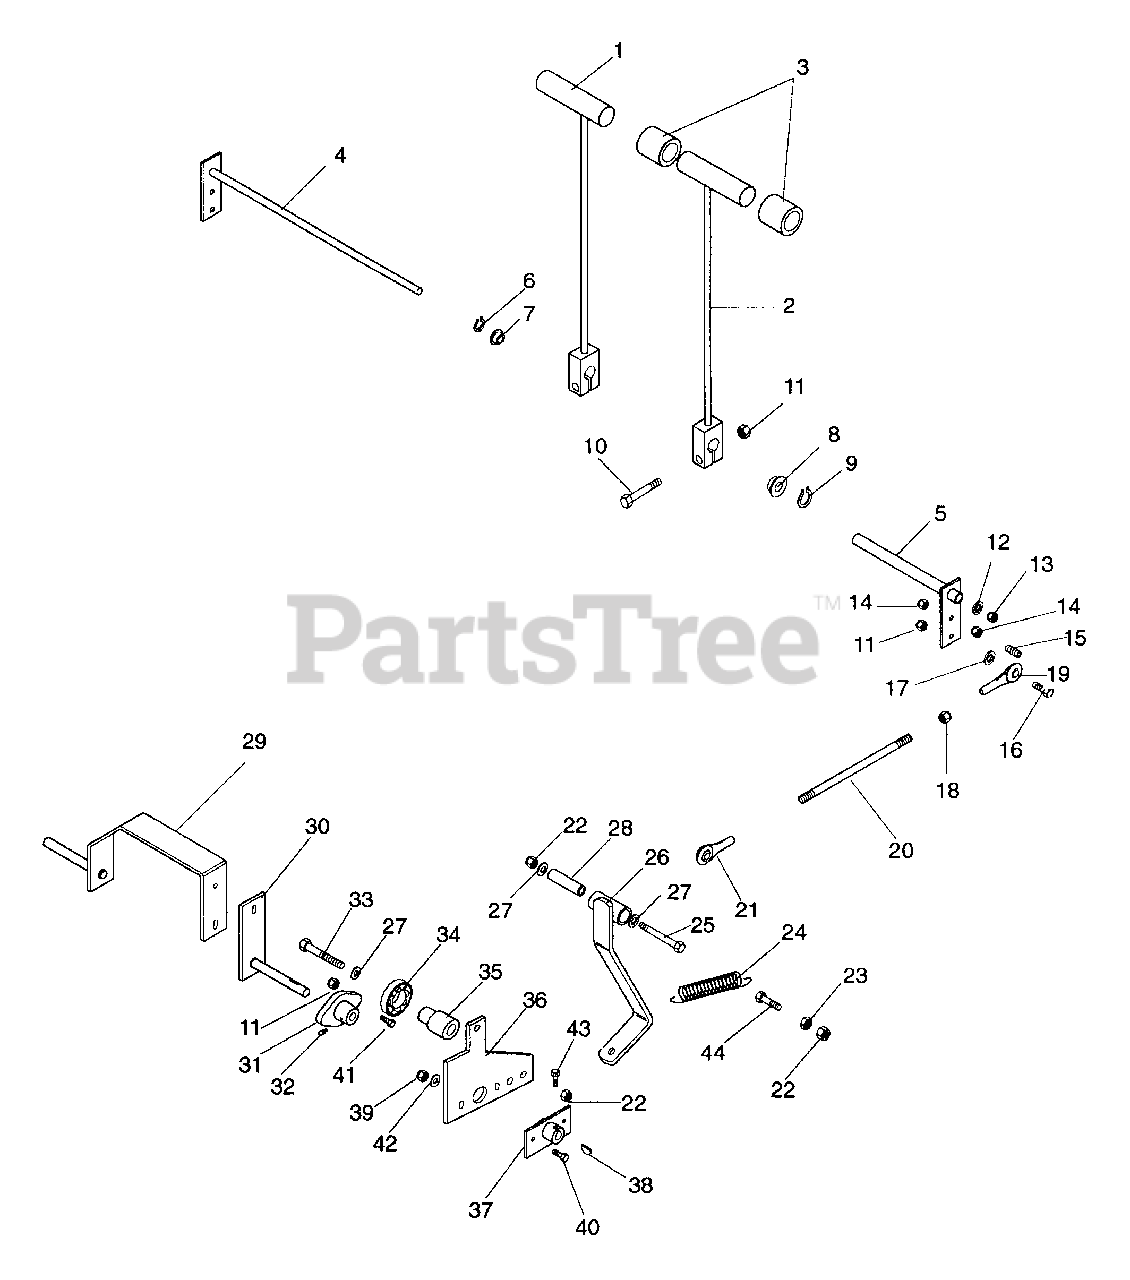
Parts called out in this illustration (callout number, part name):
1	Weldment, Steering Lever L.H.
2	Weldment, Steering R.H.
3	Grip, T-Bar
4	Weldment, Steering Rod
5	Weldment, Steering Tube
6	Ring-Retaining-External .500 x .460
7	Bushing-Flange .515 x .750 x .745 x 1.00
8	Bushing-Flange .762 x 1.0 x .580 x 1.48
9	Ring-Retaining-External .689 x .077
10	Bolt-Hex .31-18 x 1.50 Grade 5
11	Nut-Locking-Nylon .312-18 Grade 2
12	Washer-Flat-Steel .531 x 1.062 x .095
13	Nut-Locking-Nylon .50-13 Grade 2
14	Nut-Hex .312 - 18 Grade 2
15	Screw-Set .32-18 x 1.50
16	Bolt-Hex .31-18 x 1.25 Grade 2
17	Washer-Flat-Steel .344 x .688 x .065
18	Nut - 5/16-24, Hex, Plated
19	Rod End, 5/16" Female
20	Rod, Steering Adjusting
21	Rod End, 5/16 - 24 Left Hand Female
22	Nut-Locking-Nylon .375-16 Grade 2
23	Nut-Hex .375 - 16 Grade 2
24	Spring-Tens .063 x .62 x 2.75
25	Bolt-Hex .38-16 x 2.75 Grade 5
26	Weldment, Neutral Detent
27	Washer-Flat-Steel .406 x .812 x .065
28	Bushing, Steel .385 x .610 x 1.80
29	Weldment, Pump Control R.H.
30	Weldment, Pump Control L.H.
31	Bushing, Flanged Support
32	Fitting-Lube .25-28 x .256
33	Bolt-Hex .38 - 16 x 2.00 Grade 5
34	Bearing-Ball .500 x 1.375 x .437
35	Hub, Bearing Mount
36	Arm, Speed Control
37	Weldment, Neutral Adjuster
38	Key, Woodruff .13 x .75
39	Nut-Locking-Nylon .250-20 Grade 2
40	Bolt-Hex .25-20 x .75 Grade 5
41	Bolt-Hex .31-18 x 1.00 Grade 5
42	Washer-Flat-Steel .281 x .620 x .065
43	Bolt Hex .25-20 x .50 Grade 5
44	Bolt-Hex .38-16 x 1.125
